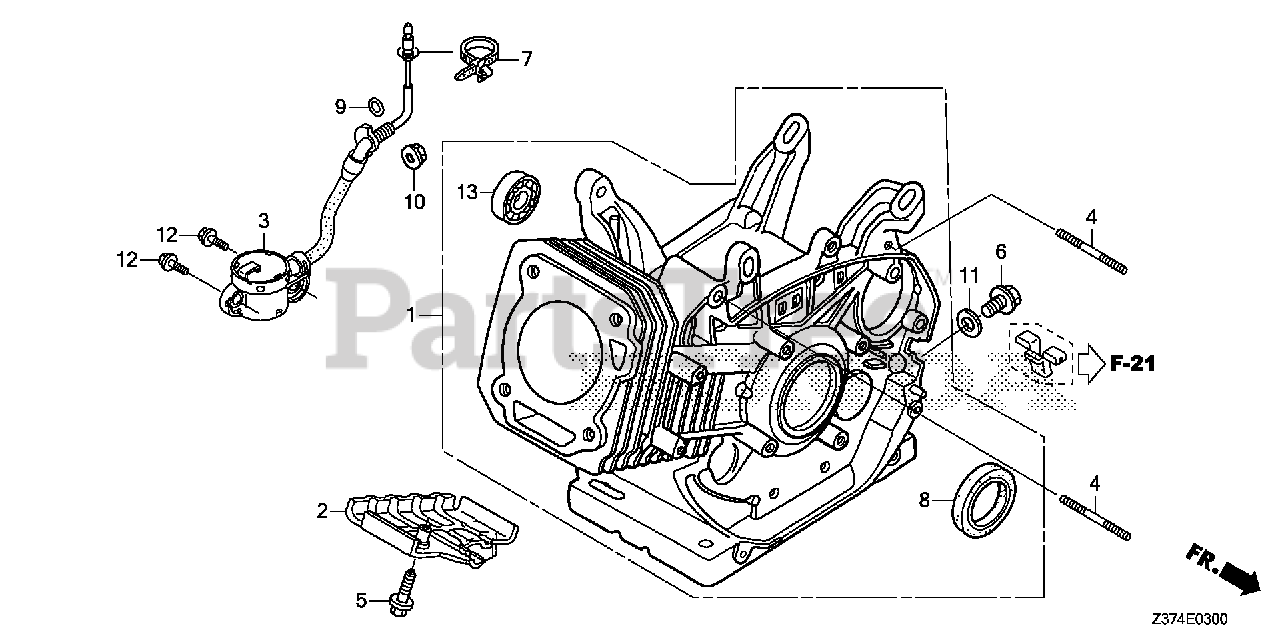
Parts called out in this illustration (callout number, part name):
1	CYLINDER ASSY.
2	SHROUD, ENGINE
3	SWITCH ASSY., OIL LEVEL
4	BOLT, STUD (6X30)
5	BOLT, FLANGE (6X25) Use up to Engine SN 2056819.
6	BOLT, DRAIN PLUG
7	BAND, CABLE
8	OIL SEAL (35X52X8) (NOK)
9	O-RING (14MM) (ARAI) Use up to Engine SN 2949254.
10	NUT, FLANGE (10MM)
11	WASHER, DRAIN PLUG (12MM)
12	BOLT, FLANGE (6X12) Use from Engine SN 2086984.
13	BEARING, RADIAL BALL (6202)
